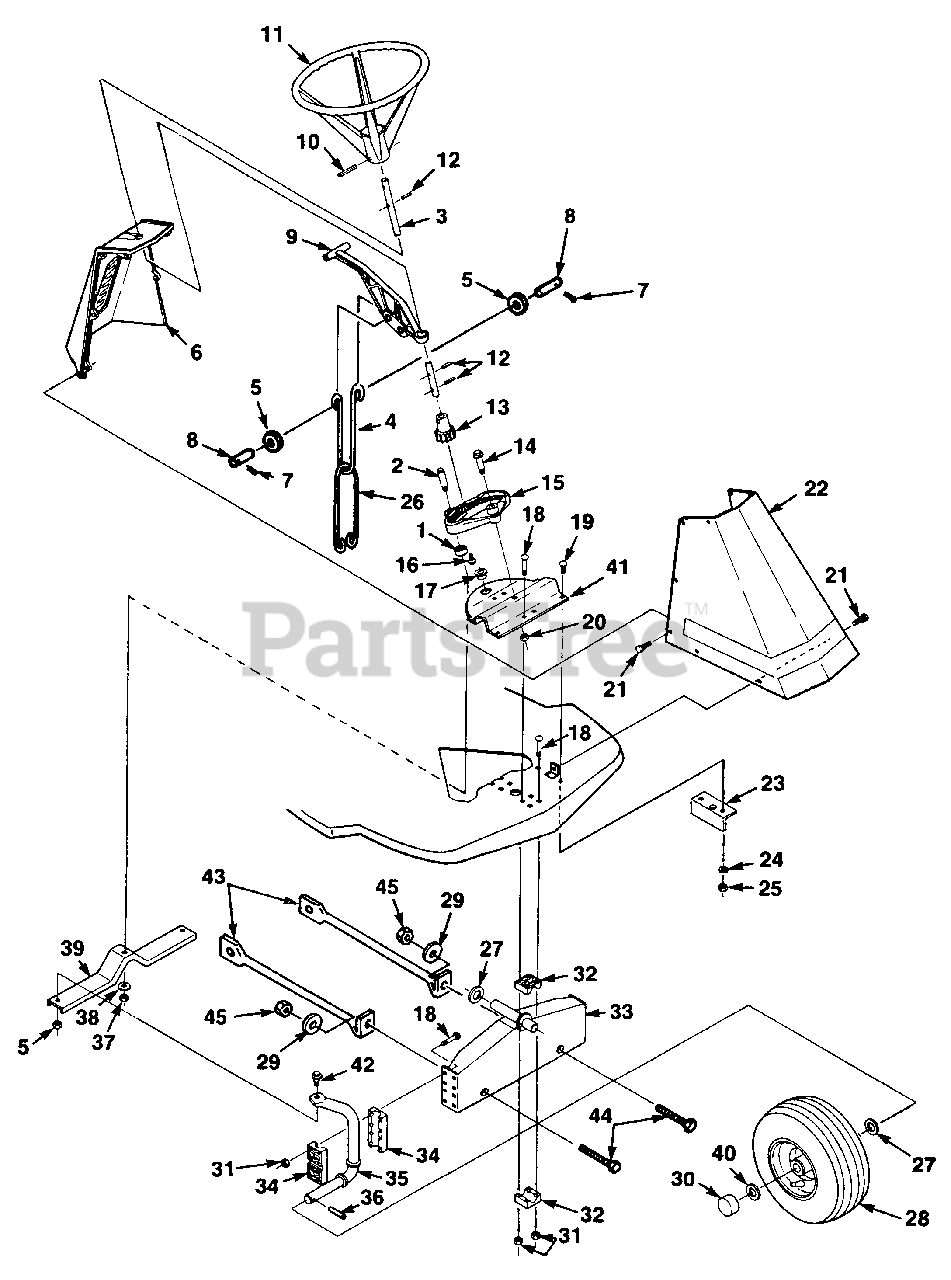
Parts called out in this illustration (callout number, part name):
1	BUSHING- Ball
2	STUD- Steer
4	LINK- Lift
5	WASHER- Flat 17/32
6	PANEL- Console
7	PIN- Cotter 1/8 x 3/4
8	PIN- Retainer
9	HANDLE- Lift
10	PIN- Roll 1/4 x 2
11	WHEEL- Steering
13	PINION- Steering
14	BOLT- Shoulder 3/8-16 x .125
15	SECTION- Steering
16	SCREW 1/4-20 x 1/2
18	BOLT- 1/4-20 x 1 3/4 carr.
19	BOLT- 1/4-20 x 3/4 Carr. Sq. Nk.
20	NUT- 3/8-16 C'lock
21	BOLT- 1/4-14 x .44 Swedge form
22	SUPPORT- Steering
24	WASHER- Lock 1/4
25	NUT- 1/4-20 hex
26	LINK- Lower lift
27	WASHER- Flat 3/16
28	WHEEL & TIRE
29	WASHER- Plain (Flat 13/32)
31	NUT- 1/4-20 hex c'lock
32	BEARING - Front axle
33	AXLE- Front
34	BEARING- Wheel spindle
35	SPINDLE- L.H. Wheel
36	PIN
37	NUT- C'Locking-hex 3/8-24
38	WASHER- Flat 13/32
39	BRACKET- Steering
41	BRACKET- Reinforcement
42	BOLT- Shoulder
43	SUPPORT- Frame axle
44	BOLT- 3/8-16 x 5/8
45	NUT 3/8-16 C'Lock
